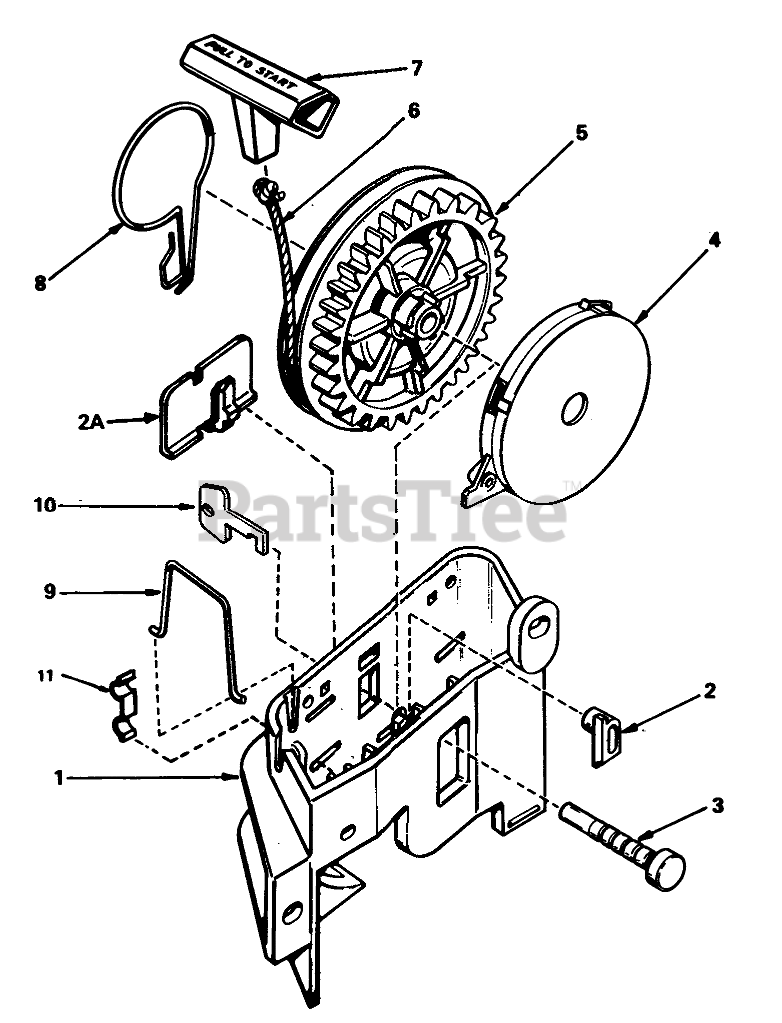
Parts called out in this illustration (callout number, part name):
1	Bracket Starter
2	Pawl, Locking Not used on all engine models)
2A	Clip, Starter Bracket (Used On Starters Not Equipped With Pawl, Ref. No. 2)
3	Pin-Pulley
4	Spring Assy., Rewind (Incl. #3)
6	Rope Starter (Length 65" & 9/64" Dia.)
7	Hub Spring
9	Clip-Rope
10	Key (Not Used On All Engine Models
11	Washer-Thrust
